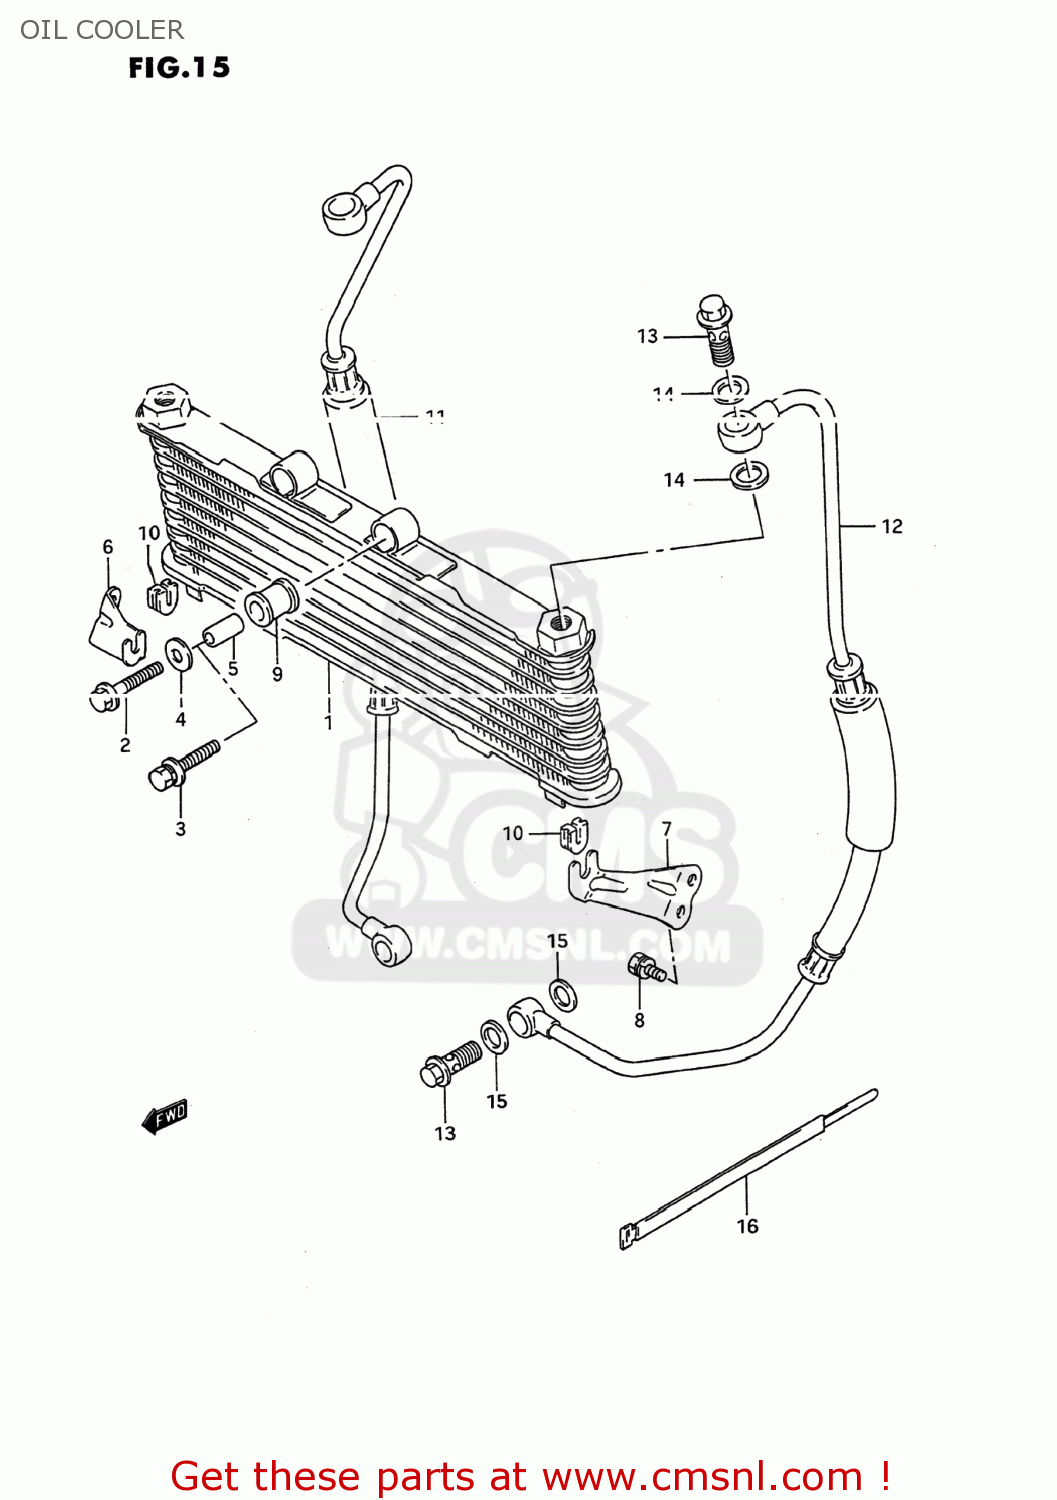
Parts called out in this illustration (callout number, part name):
1	COOLER ASSEMBLY,OIL
2	BOLT
3	BOLT(8X40)
4	WASHER(8.5X23X1.2)
5	SPACER (8.8X12X24.5)
6	BRACKET,OIL COOLER,R
7	BRACKET,OIL COOLER,L
8	BOLT
9	CUSHION,OIL COOLER NO.1
10	CUSHION,OIL COOLER NO.2
11	HOSE,OIL
12	HOSE,OIL
13	BOLT UNION
14	GASKET(16X22X2) (NAS)
15	GASKET(16X22X2) (NAS)
16	CLAMP(L:250)
